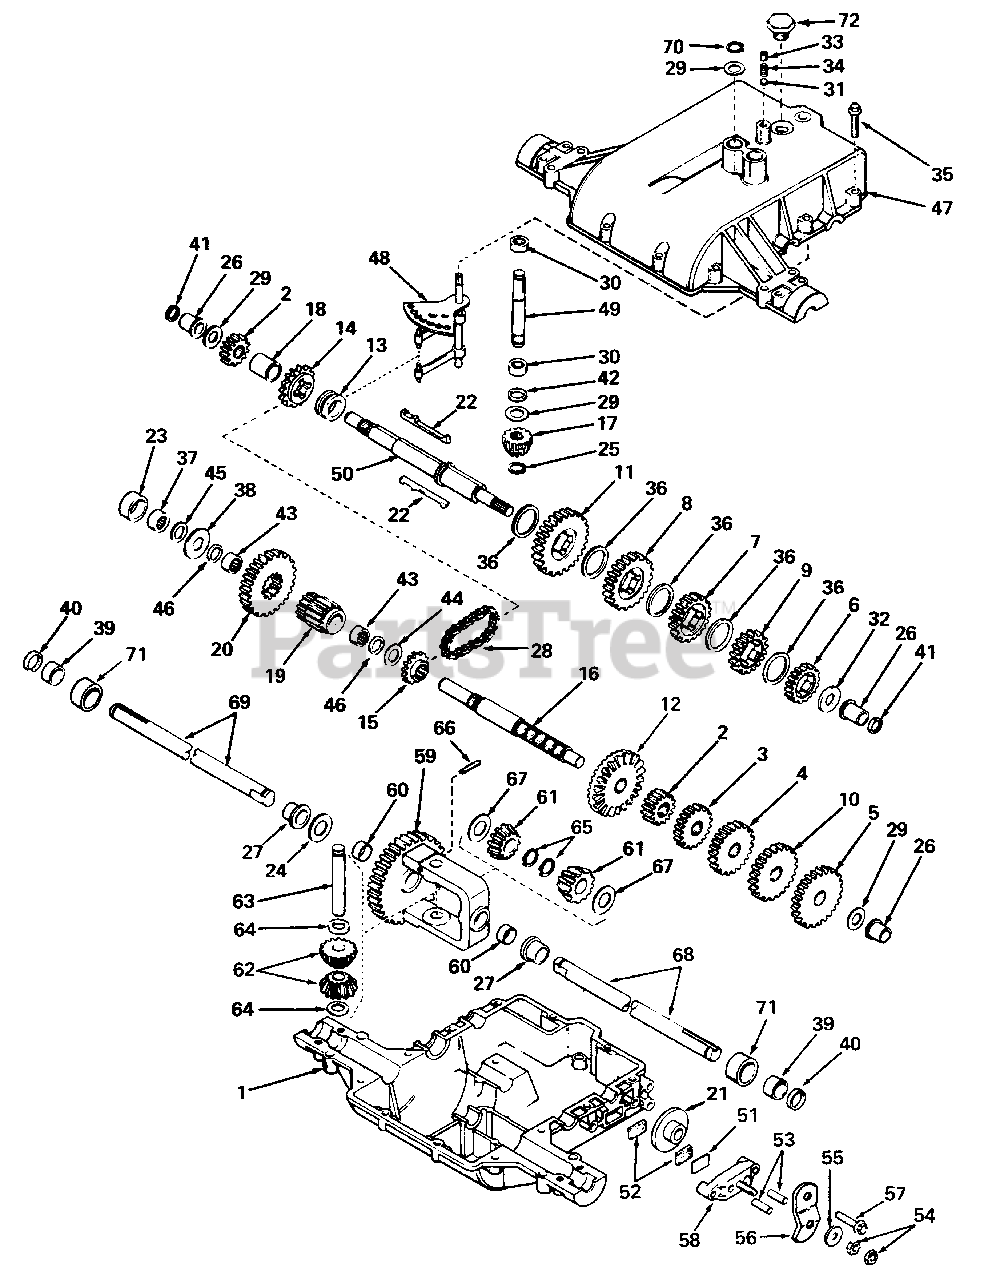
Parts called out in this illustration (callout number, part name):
1	CASE, Transaxle
2	GEAR, Spur (15 Teeth)
3	GEAR, Spur (20 Teeth)
4	GEAR, Spur (25 Teeth)
5	GEAR, Spur (30 Teeth)
6	GEAR, Spur (20 Teeth)
7	GEAR, Spur (25 Teeth)
8	GEAR, Spur (30 Teeth)
9	GEAR, Spur (22 Teeth)
10	GEAR, Spur (28 Teeth)
11	GEAR, Spur (35 Teeth)
12	GEAR, Bevel (42 Teeth)
13	COLLAR, Shift
14	SPROCKET (18 Teeth)
15	SPROCKET (9 Teeth)
16	SHAFT, Counter
17	BEVEL PINION, Input
19	PINION, Output
20	GEAR, Output
21	DISK, Brake
25	RING, Retaining
26	BUSHING, Flanged
27	BUSHING, Flanged
28	CHAIN, Roller (No. 41 chain, 24 links)
29	WASHER, Thrust
30	BEARING, Needle
31	BALL, Steel
32	WASHER, Thrust
33	SETSCREW, 3/8-16 x 3/8
35	SCREW, Hex Hd., Thd. Form., 1/4-20 x 1-1/4
36	WASHER, Thrust
37	BEARING, Needle
38	WASHER, Flat
39	BEARING, Needle
40	SEAL, Oil
41	RING, Square Cut
42	RING, Square Cut
43	BEARING, Needle
44	WASHER, Flat
45	RING, Square Cut
46	RING, Square Cut
47	COVER, Transaxle
48	ROD & FORK ASSY., Shift
49	SHAFT, Input
50	SHAFT, Brake
51	PLATE, Brake Pad
52	PAD, Brake
53	PIN, Dowel
54	LOCKNUT, 5/16-24
55	WASHER, Flat
56	LEVER, Brake
57	SCREW, Hex Hd., Thd. Form., 1/4-20 x 1-1/4
58	HOLDER, Brake Pad
59	GEAR ASSY., Differential (Incl. 2 of No. 60)
61	GEAR, Bevel
62	PINION, Bevel
63	PIN, Drive
64	WASHER, Thrust
65	RING, Retaining
66	PIN, Roll
67	WASHER, Thrust
68	AXLE (15-1/8" Long)
69	AXLE (12-1/8" Long)
70	RING, Retaining
